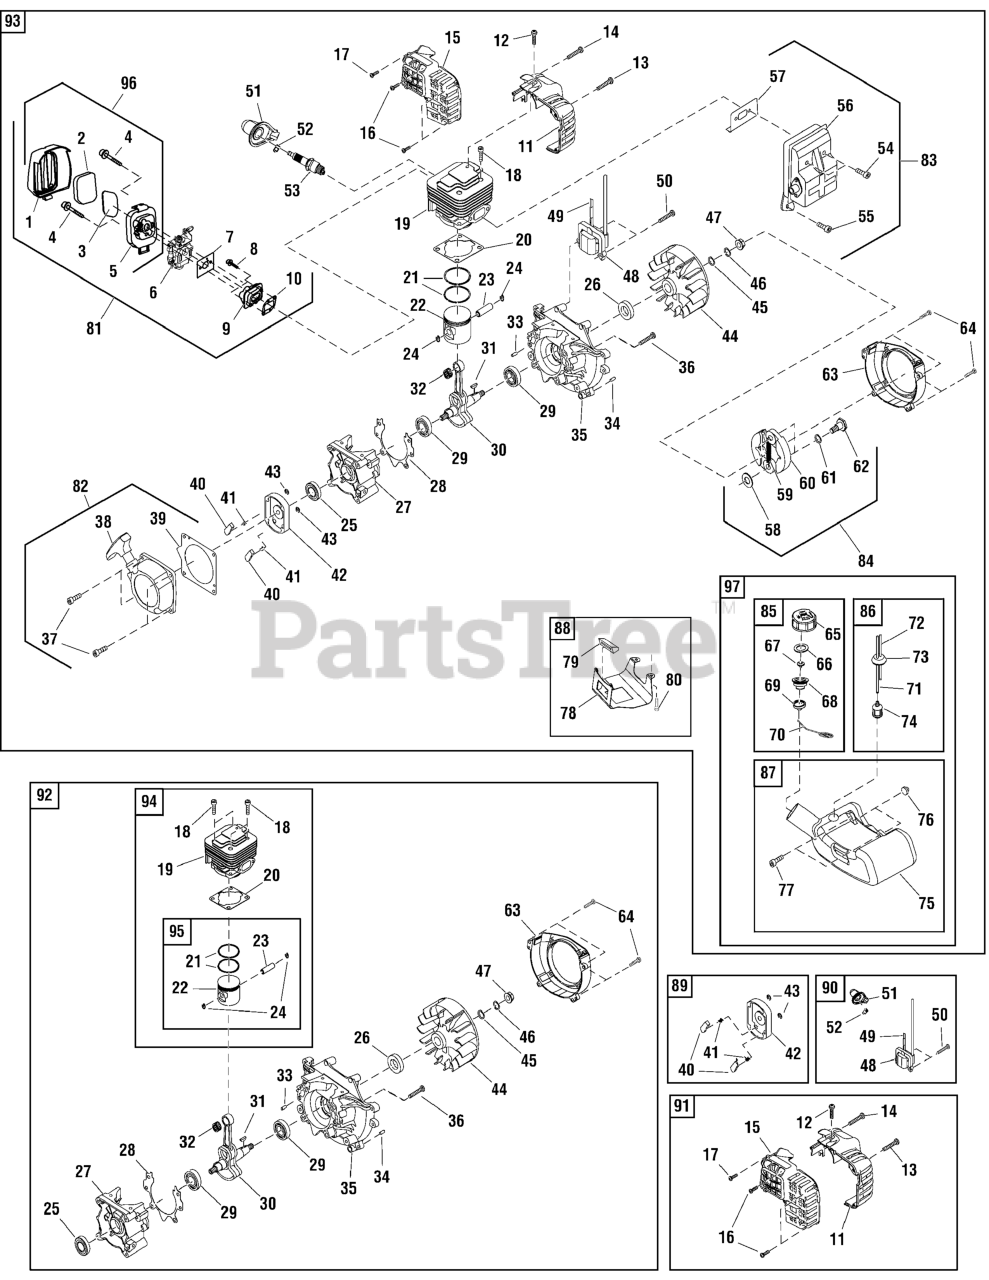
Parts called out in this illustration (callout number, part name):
1	COVER, Cleaner, Outer
2	FILTER
3	BRACKET, Filter Net
4	BOLT, M5 x 55
5	BRACKET, Air Cleaner
6	CARBURETOR
7	GASKET, Carburetor
8	BOLT, M5 x 25
9	ADMITTING PIPE
10	GASKET, Admitting Pipe
11	SHROUD, Front
15	SHROUD, Back
16	SCREW, Self Tapping, 5 x 20
17	SCREW, Self Tapping, 4.2 x 25
18	BOLT, M5 x 20
19	CYLINDER
20	GASKET, Cylinder
21	RING, Piston
22	PISTON
23	PIN, Piston
24	RING, Pin Retain
25	SEAL, Oil, 11.7 x 22 x 7
26	OIL SEAL, 30 x 14.7 x 7
27	CRANK CASE, Rear
28	GASKET, Crank Case
29	BEARING, 6201/P6
30	CRANKSHAFT
31	KEY, 3 x 5 x 13
32	BEARING, Needle
33	PIN, Cylindrical, B5 x 12
34	PIN, Cylindrical, B4 x 10
35	CRANK CASE, Front
38	STARTER
39	STARTER PAD
40	STARTER CINCH
41	SPRING, Starter
42	STARTER BOX
43	RING, Retainer
44	FLY WHEEL
45	WASHER, Flat, Dia. 8
46	WASHER, Spring, Dia. 8
47	NUT, M8
48	MAGNETO COIL
49	CORD, Magneto
51	BOOT, Spark Plug
52	CLIP, Spark Plug
53	SPARK PLUG
54	* BOLT, M5 x 55-10.9
56	MUFFLER
57	GASKET, Muffler
58	WASHER, B
59	SPRING, Clutch
60	EXPANDER, Complete
61	WASHER, Wave
62	SCREW, Shaft
63	COVER, Fan
64	BOLT, M5 x 25
65	LID, Fuel Tank
66	GASKET
67	INLET
68	LID, Fuel Tank, Inner
69	COVER, End
70	CHAIN, Fuel Cap
71	PIPE, Fuel
72	PIPE, Soft PVC
73	PLUG, Fuel Line
74	FILTER, Fuel
75	FUEL TANK
76	PLUG, Rubber
78	BRACKET, Fuel Tank
79	COVER, Rubber
81	KIT, Air Cleaner & Carburetor
82	KIT, Starter Assembly
83	KIT, Muffler Assembly
84	KIT, Expander Assembly
85	KIT, Fuel Cap Assembly
86	KIT, Fuel Line Assembly
87	KIT, Fuel Tank Assembly
88	KIT, Tank Bracket Assembly
89	KIT, Start Reel Assembly
90	KIT, Magneto Assembly
91	KIT, Shroud Assembly
92	KIT, Cylinder Assembly
93	ENGINE ASSEMBLY, Complete
94	KIT, Cylinder Head
95	KIT, Piston
96	KIT, Air Cleaner
97	KIT, Fuel Tank & Cap
